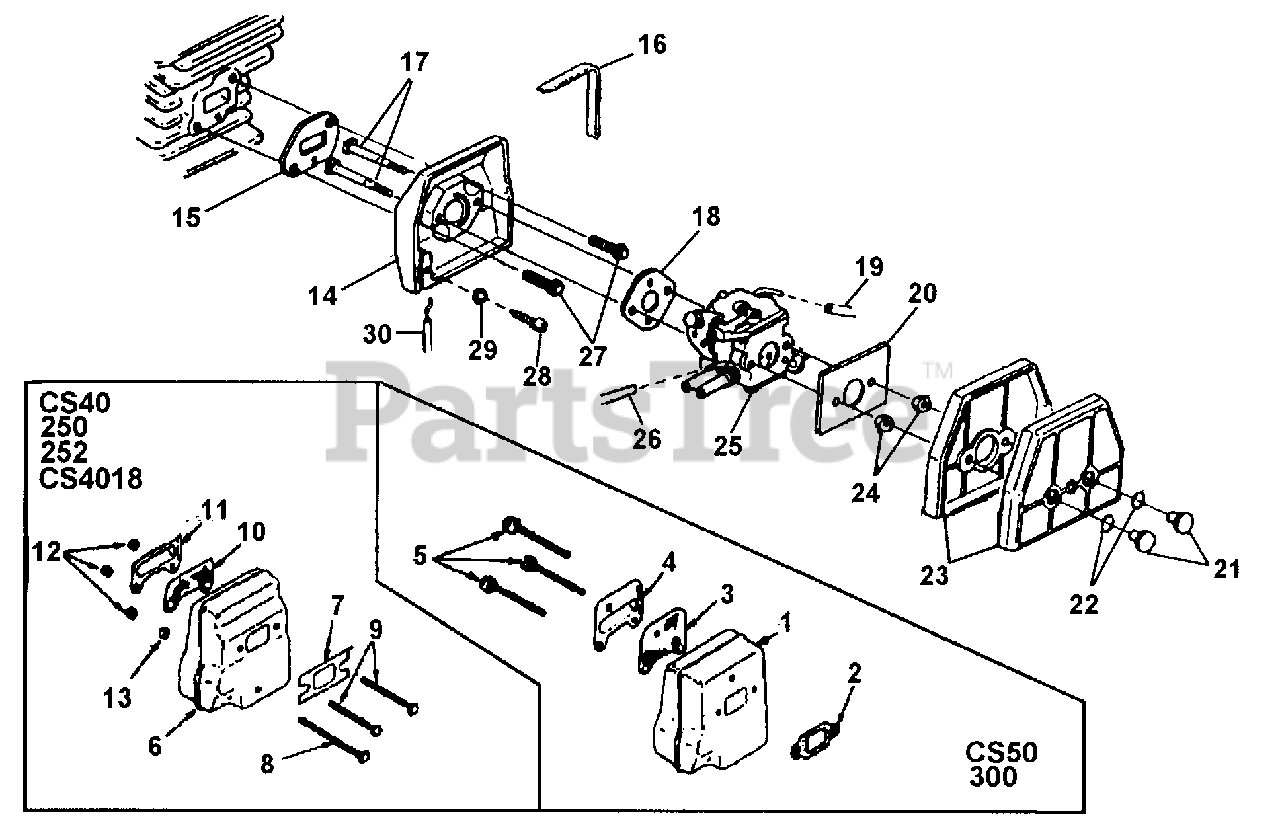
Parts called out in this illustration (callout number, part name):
1	MUFFLER - Complete
2	GASKET Muffler
3	SCREEN- Spark Arrestor
4	COVER- Exhaust
5	SCREW-Sems (10-24 x 2 1 /4)
6	MUFFLER - Complete
7	GASKET Muffler
8	SCREW- Square Hd. (10-32 x 2 1/2)
9	SCREW- Square Hd. (10-32 x 2 1 /4)
10	SCREEN-Spark Arrestor
11	COVER- Exhaust
12	NUT Locking (10-32)
13	WASHER- Flat (#12)
14	SPACER-Carburetor
15	GASKET Carburetor Spacer
16	FOAM- Adhesive
17	SCREW- Carburetor Retainer
18	GASKET Carburetor
19	TUBING-Rubber (9")
20	RETAINER PLATE
21	RETAINER NUT Filter
22	"O" RING
23	AIR FILTER
24	NUT Hex (8-32)
25	CARBURETOR (Walbro WT224)
26	TUBING- Rubber (4 3/4")
27	SCREW Mach. Hex Hd. (8-32 x 7/8")
28	SCREW Thread Form (6-19 x 5/8")
29	WASHER Flat (#6)
30	CABLE Throttle
